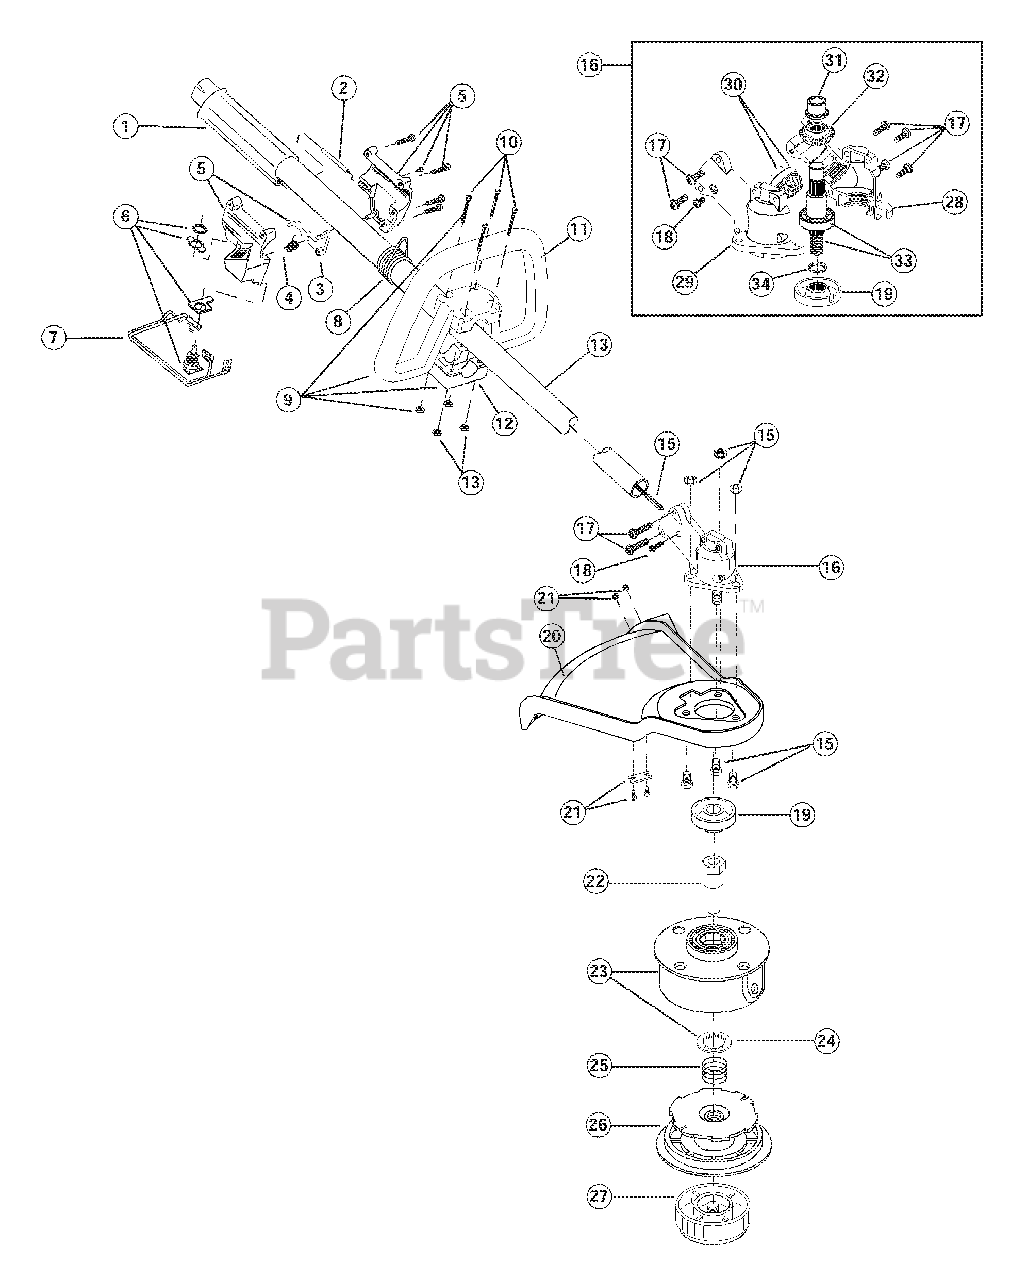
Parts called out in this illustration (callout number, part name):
2	Throttle Cable Assembly
3	Throttle Trigger
4	Throttle Trigger Spring
5	Throttle Trigger Assembly
6	Switch Assembly
7	Wire Lead Assembly
8	Shoulder Harness Clamp
9	Loop Handle Assembly
12	Nut
13	Drive Shaft Housing Assembly
15	Shield Mount Screw Assembly
16	2 piece Gearbox Assembly
17	Gearbox Mounting Hardware
18	Anti-Rotation Screw
19	Blade Driver
20	Shield and Blade Assembly
21	Blade Assembly
22	Spool Shaft
23	Outer Spool & Eyelet Assembly
24	Retainer
27	Bump Head Knob Assembly
28	Left Housing
29	Right Housing
30	Pinion Gear Assembly
31	Output Shaft Bushing
32	Output Shaft Gear
33	Output Shaft Assembly
34	O-Ring
